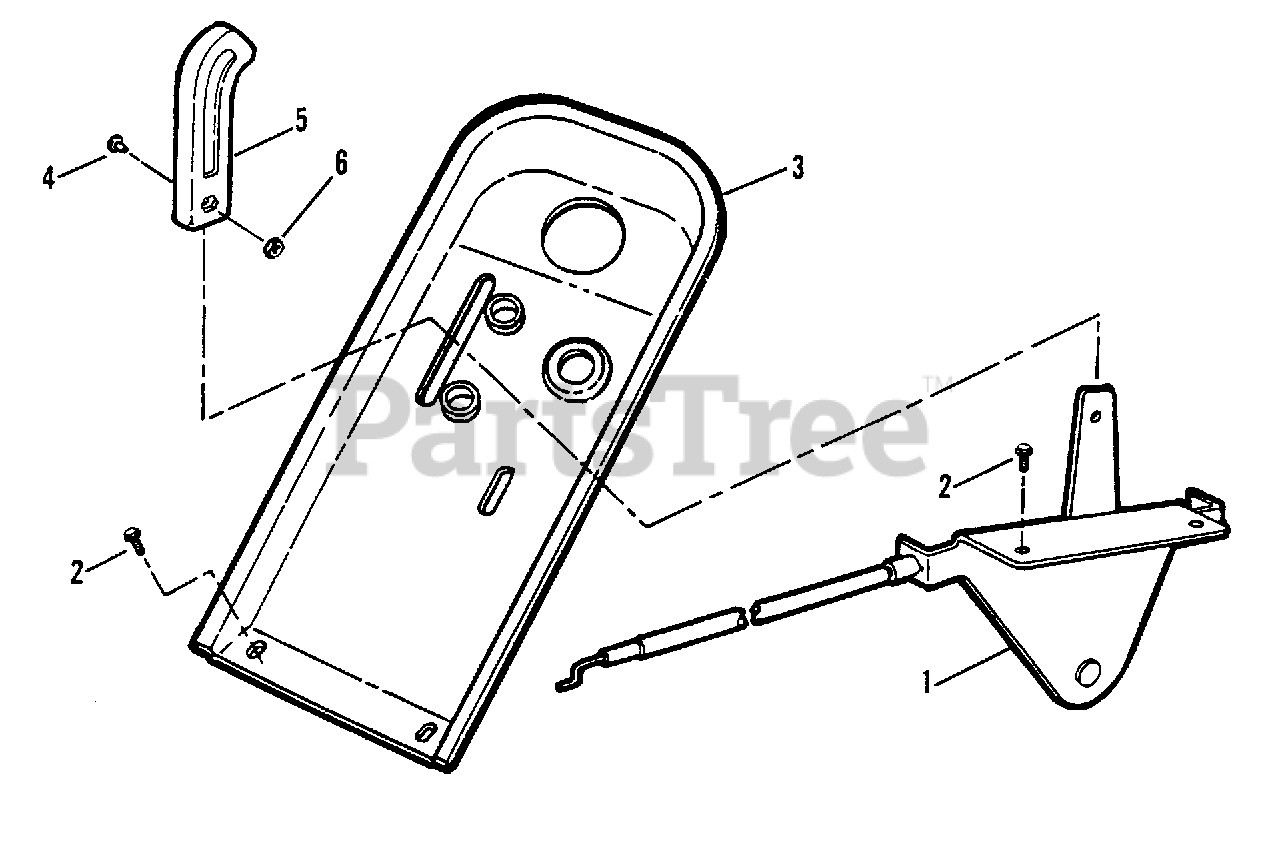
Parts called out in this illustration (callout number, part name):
1	CONTROL, Throttle (Briggs Engines)
2	SCREW, #10-24 x 1/2" Hex Washer Self-Tap (Torx)
3	COVER, Dash Panel (Electric Start)
4	SCREW, #8-32 x 3/8" Cross Recessed Fillister Head
5	KNOB, Throttle Control
6	NUT, #8-32 Hex, Grade 2 or B
